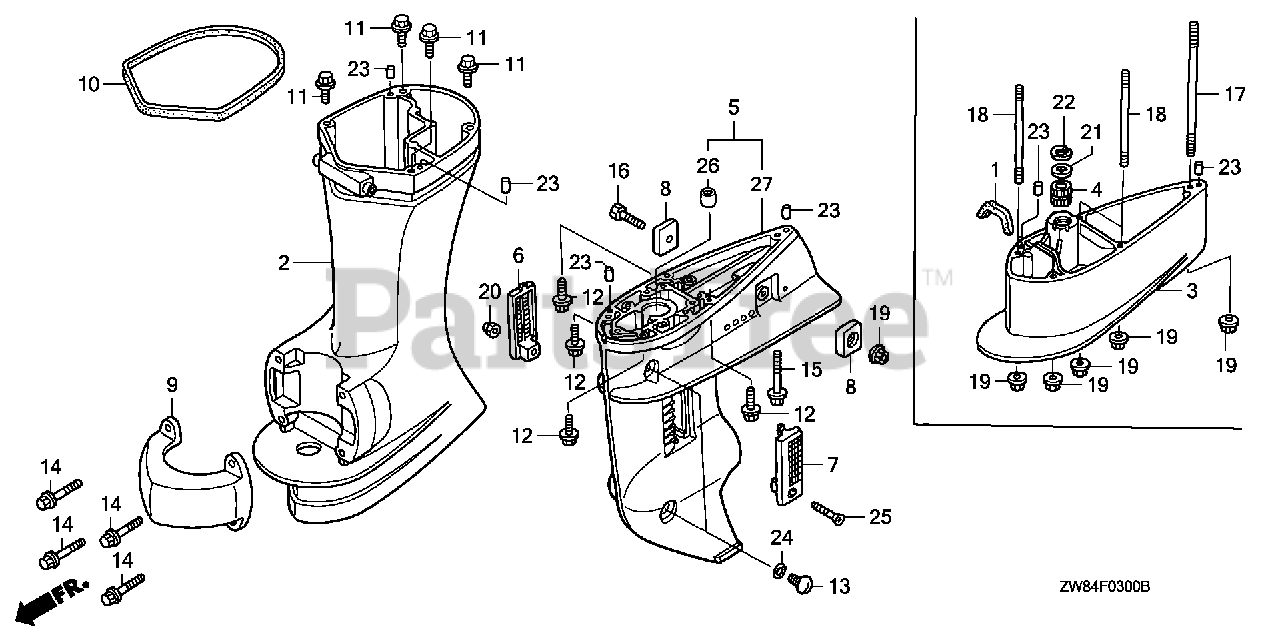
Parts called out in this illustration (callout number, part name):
2	CASE, EXTENSION *NH282MU* (S) (OYSTER SILVER METALLIC-U)
5	CASE, GEAR *NH282MU* (S) (OYSTER SILVER METALLIC-U) (NOT AVAILABLE)
6	SCREEN, R. WATER
7	SCREEN, L. WATER
8	METAL, ANODE
9	HOUSING, MOUNTING (LOWER) *NH282MU* (OYSTER SILVER METALLIC-U)
10	RUBBER, COVER (LOWER)
11	BOLT, FLANGE (8X35)
12	BOLT, FLANGE (6X23)
13	BOLT, OIL CHECK
14	BOLT, FLANGE (6X20)
15	BOLT, FLANGE (6X75)
16	BOLT, HEX. (6X25)
19	NUT, SELF-LOCK (6MM)
20	NUT, SELF-LOCK (5MM)
23	PIN, DOWEL (6X10)
24	O-RING (5.5X1.5)
25	SCREW, OVAL (5X28)
26	BUSH, PINION GEAR (13X18X20)
27	CASE, GEAR *NH282MU* (OYSTER SILVER METALLIC-U)
